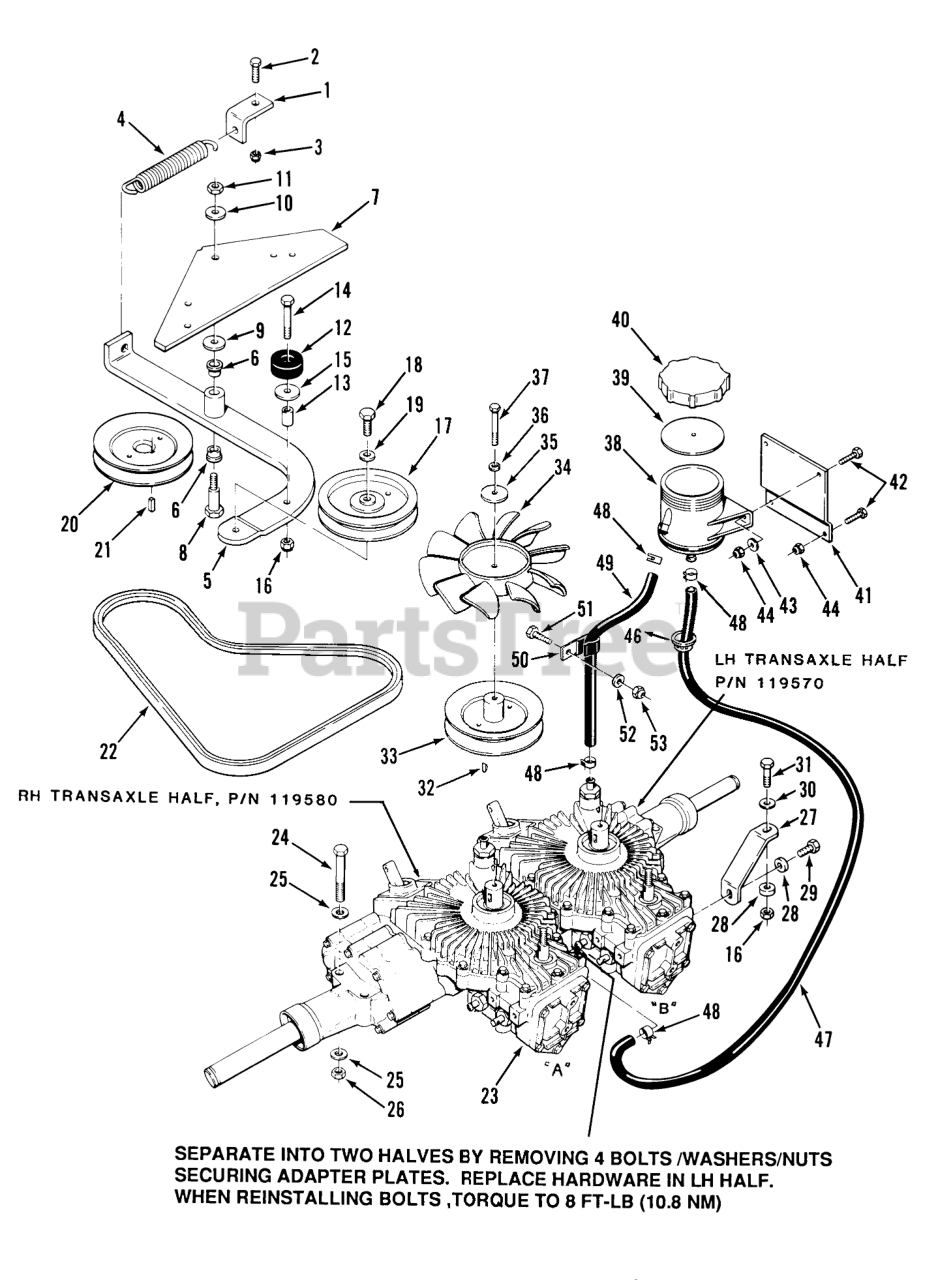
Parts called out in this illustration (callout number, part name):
1	BRACKET-SPRING
2	Bolt
3	Nut
4	SPRING-EXTENSION
5	Arm-Idler
6	BUSHING
7	Stiffener
8	BOLT-SHOULDER
9	WASHER
10	Washer
11	Nut
12	BUMPER
13	SPACER
14	Bolt 5/16-18 x 2
15	WASHER
16	Nut
17	PULLEY IDLER
18	BOLT
19	Washer
20	PULLEY
22	V-BELT
23	Transaxle Assembly
24	Bolt
25	Washer
26	NUT
27	BRKT-HYDRO SIDE
28	WASHER-SPECIAL
29	Bolt
30	WASHER 5/16 SAE
31	Bolt
32	KEY WOODRUFF
33	PULLEY
34	FAN-7"
35	WASHER
36	Washer
37	Bolt 1/4-20 x 2
38	ASS'Y-RESERVOIR
39	COVER GASKET
40	Cover
41	BRKT-RESERVOIR R
42	Bolt
44	Nut
46	BUSHING-NYLON 1.093
47	HOSE - 24" OF 114702
47	HOSE 3/8 I.D. X 14
48	CLAMP
49	HOSE - 9.5" OF 114702
49	HOSE - 12" OF 114702
50	PIN HITCH UPPER LINK
51	Bolt
52	WASHER 5/16 SAE
53	Nut
